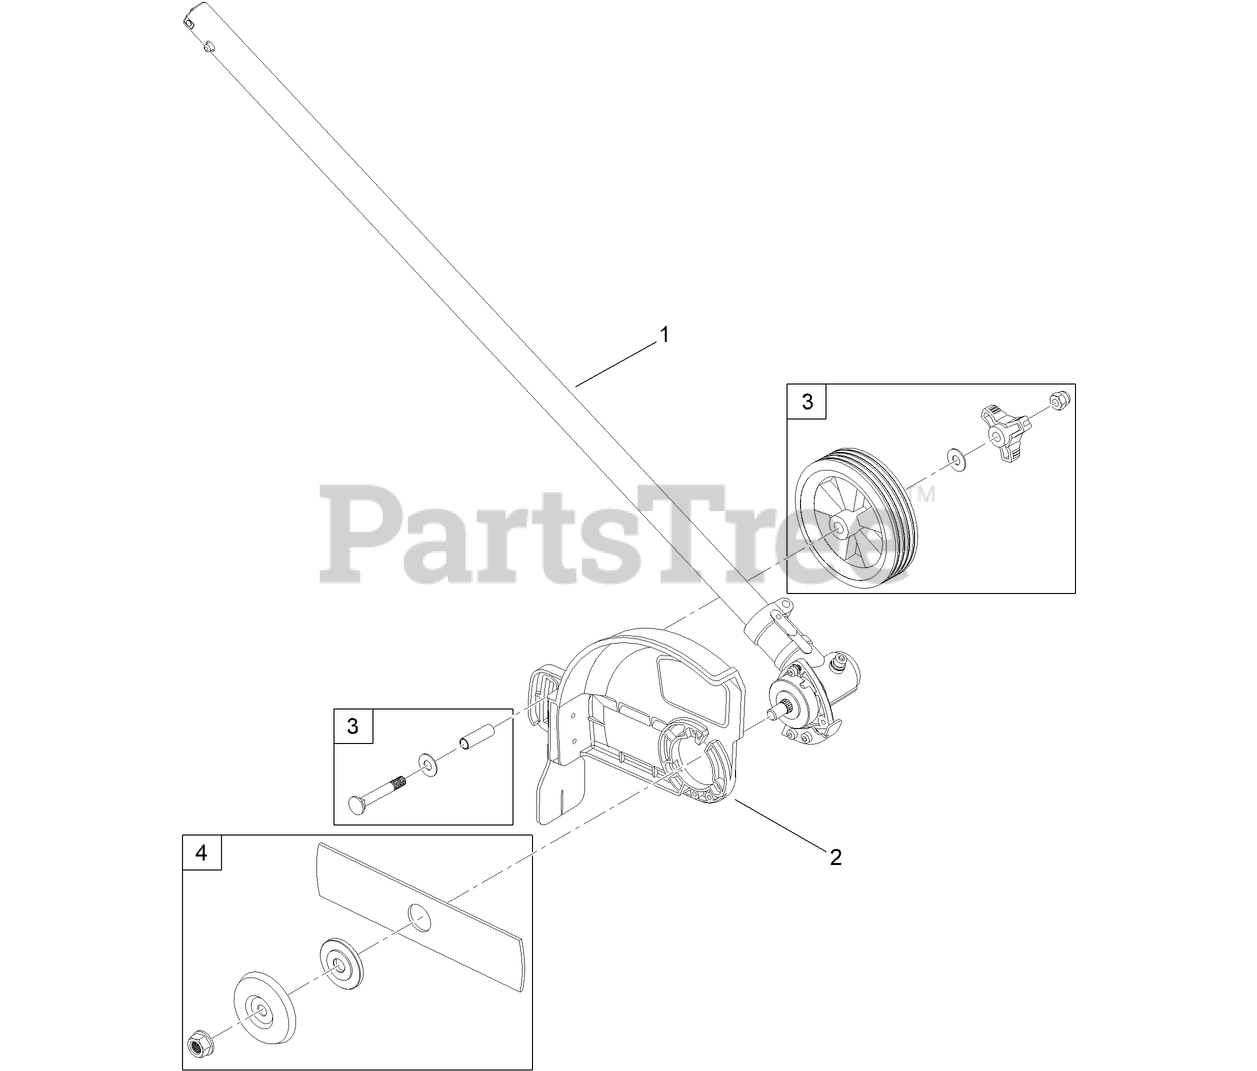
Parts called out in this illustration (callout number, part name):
1	SHAFT-EDGER
3	WHEEL ASM
4	BLADE ASM
